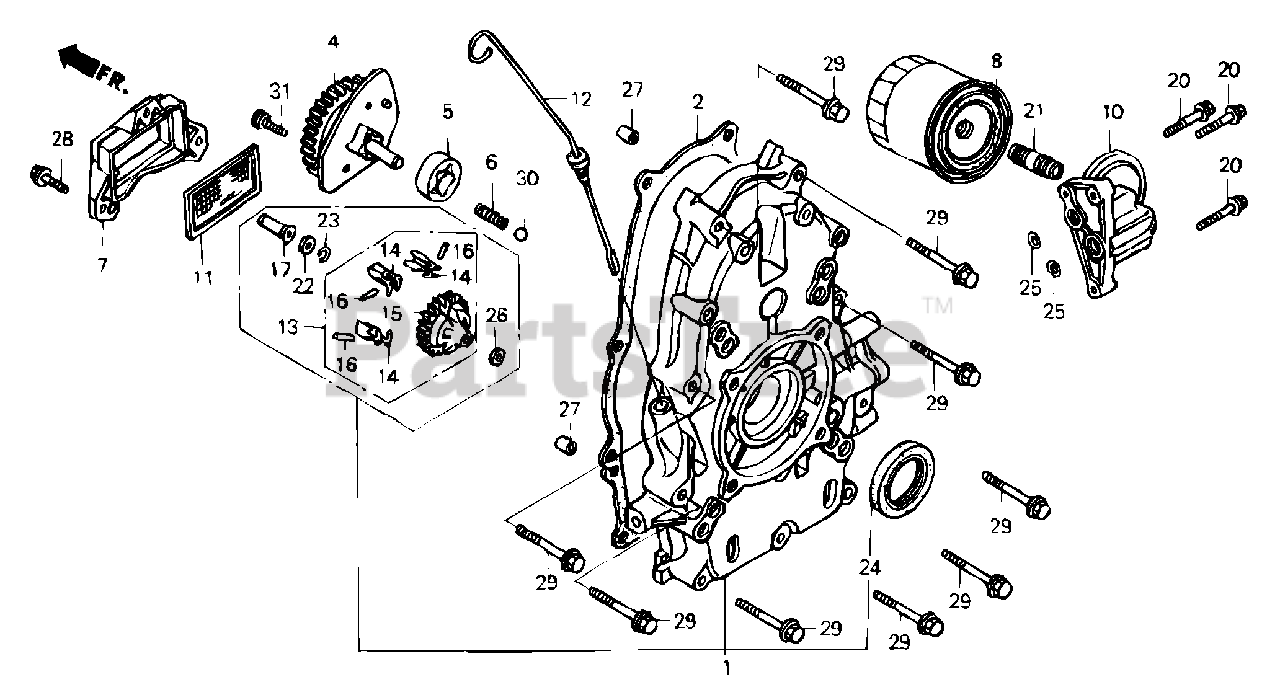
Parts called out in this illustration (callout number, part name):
1	Cover Assembly, Crankcase (Q-type)
2	Gasket, Case Cover
4	Cover Assembly, Oil Pump
5	Rotor, Oil Pump (Outer)
6	Spring, Relief Valve
7	Cover, Oil Filter
8	Filter, Oil
10	Base, Oil Filter
11	Screen, Oil Filter
12	Dipstick, Oil
13	Governor Assembly
14	Weight, Governor
15	Holder, Governor Weight
16	Pin, Governor Weight
17	Slider, Governor
20	Bolt, Flange (6x28)
21	Holder, Oil Filter
22	Washer (6x16)
23	Clip, Governor Holder
24	Oil Seal (38x58x9)
25	O-ring (11.8x2.4)
26	Washer, Plain (6mm)
27	Pin A, Dowel (8x14)
28	Bolt, Flange (6x20)
29	Bolt, Flange (8x50)
30	Ball, Steel (#12) (3/8)
31	Bolt, Socket (6x16)
